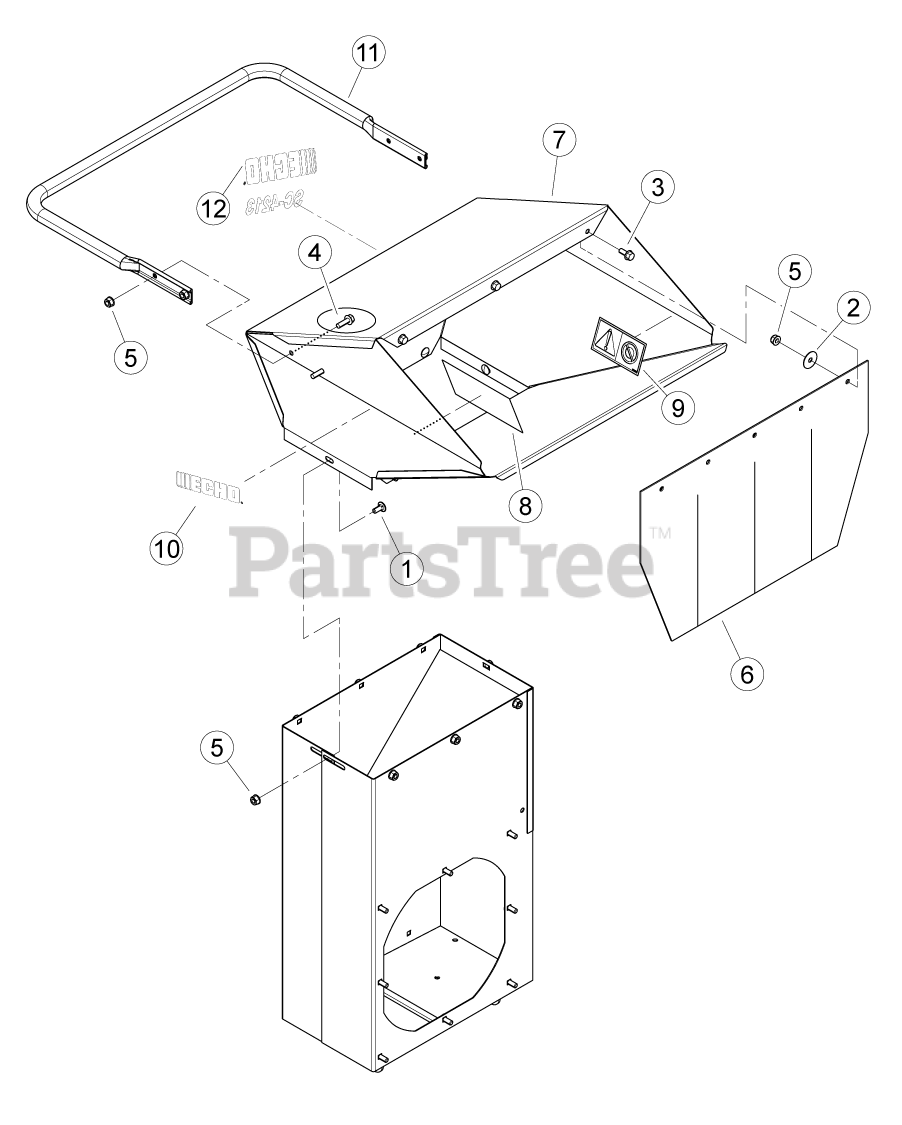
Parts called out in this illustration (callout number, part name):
1	BOLT, 5/16-18 × 3/4 SN GR5 CRG
2	WASHER, 5/16" FENDER ZP
3	BOLT, 5/16 × 3/4 FLANGE NC
4	BOLT, 5/16 × 1 FLANGE NC
5	NUT, 5/16-18 NYLOCK FLANGE
6	BELTING, RENTAL HOPPER
7	ASSEMBLY, WIDE BODY RENTAL HOPPER W/ DECALS
8	DECAL, BLADE DANGER ISO
9	DECAL, SHREDDER SIZE ISO
10	DECAL, ECHO
11	HANDLE, RENTAL HOPPER
12	DECAL, MODEL SC-4213
